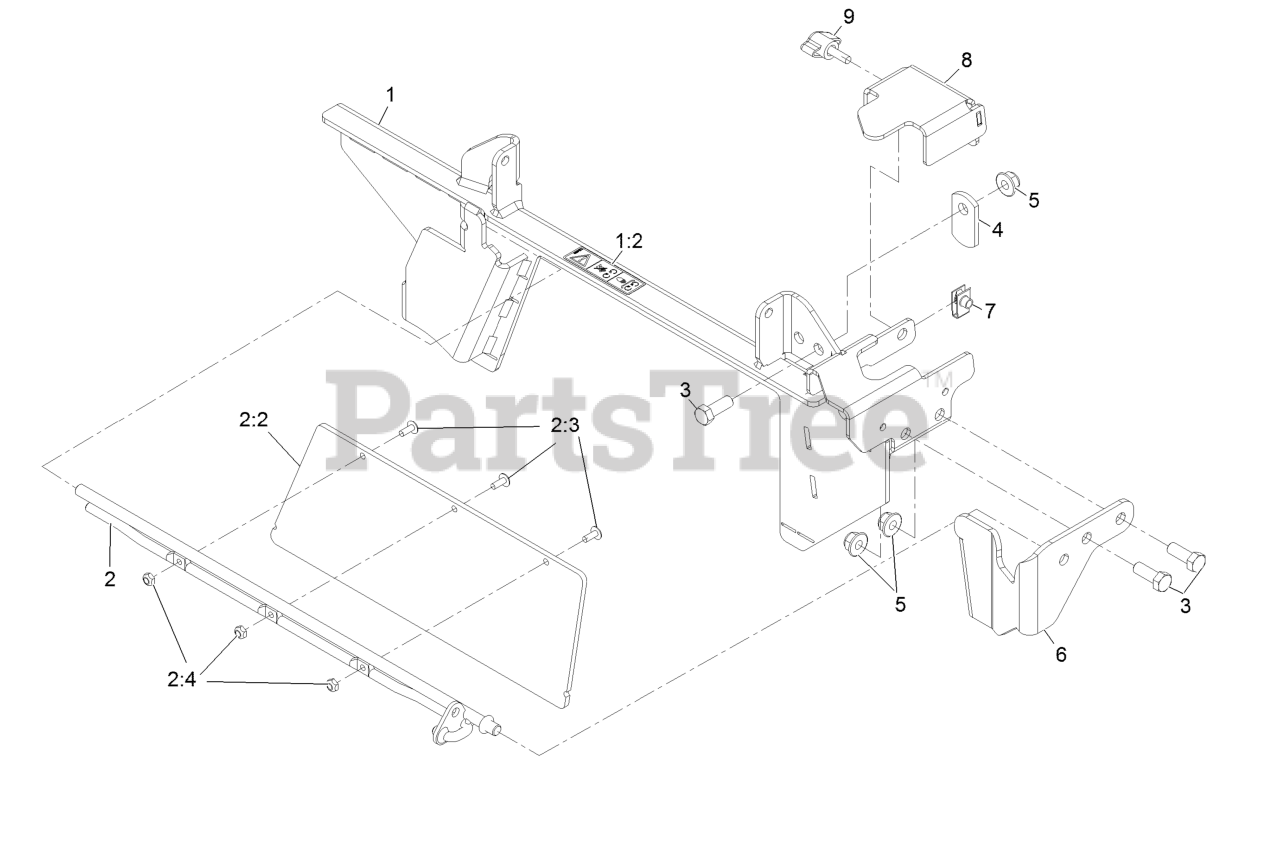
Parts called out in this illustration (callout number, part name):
1	Ocd Frame ASM W/ Decals
1:2	Decal, Cover Missing
2	Ocd Gate ASM
2:2	Gate-Ocd
2:3	Screw-Truss HD #10-24 X 1/2
2:4	Nut-Nyloc #10-24 Thin
3	Screw-HH 3/8-16 X 1
4	Latch-Catcher, Grass
5	Nut-Nyloc 3/8-16 Flg
6	Brkt,Chute Front
7	Nut-Retainer-Panel 1/4-20
8	Bracket, Cable Mount
